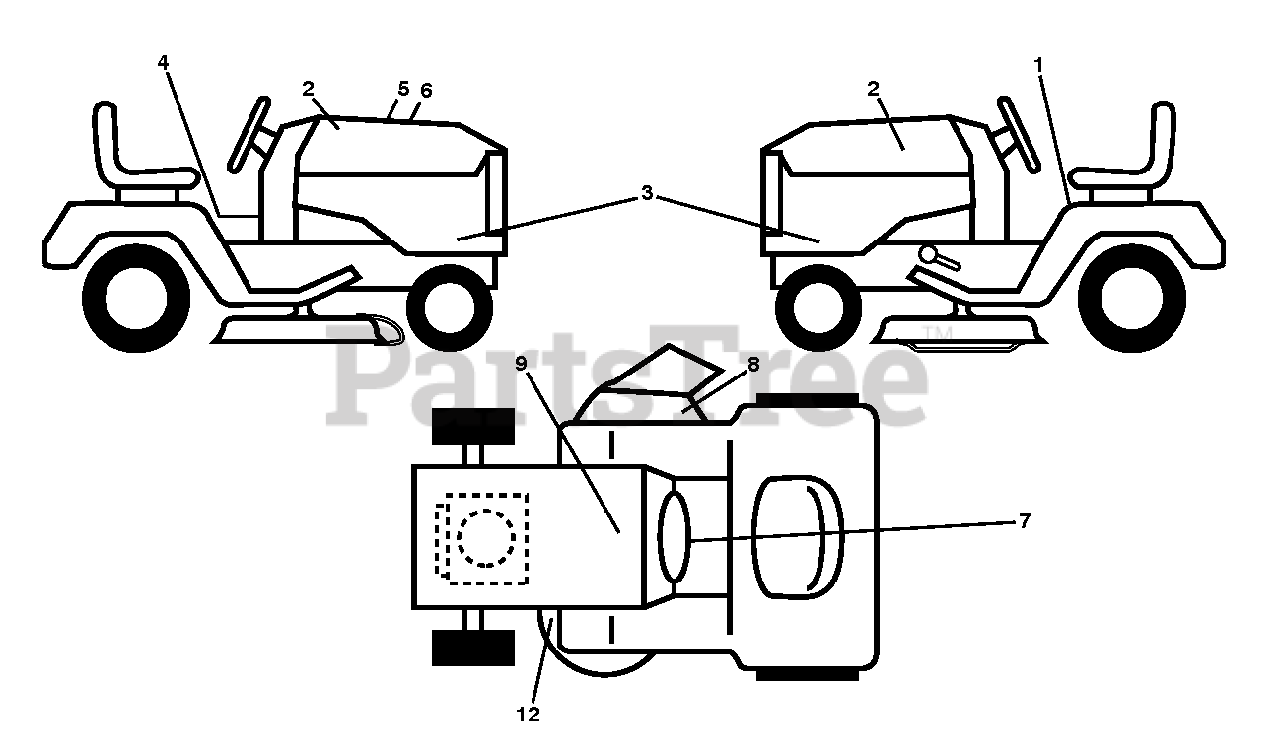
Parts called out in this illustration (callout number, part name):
1	DECAL.FENDER.WARNING.ENGLISH
2	DECAL.BADGE.170MM.TEXTLOGO.
3	DECAL.SDPNL.HUSQGT2.YTH12K26.2
4	DECAL, WARNING SPARK ARRESTOR
5	DECAL.WARNING.CUST.RESP.E85.
7	LABEL.EMISS.CALIF.HUSQVARNA
8	DECAL.MOWER.WARN.KEEP.HAND.AWY
9	DECAL BTRY SYMBOLS
12	DECAL.V-BELT.SCH.42/46"MEC/ELE
